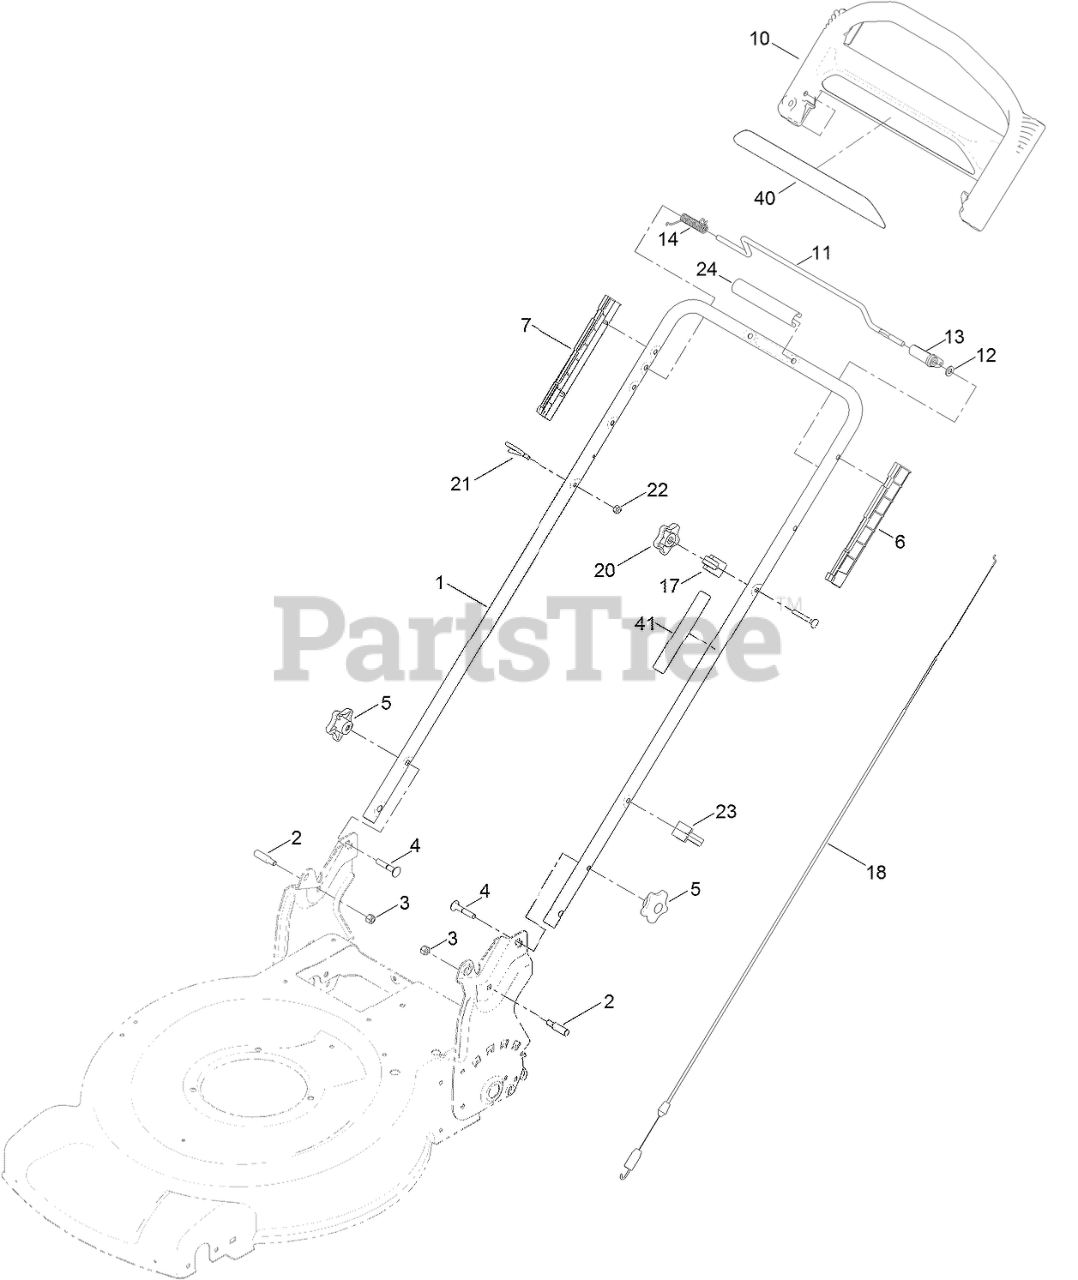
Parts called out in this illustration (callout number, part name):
2	BOLT-SHOULDER
3	NUT-LOCK, NI
4	SCREW-CARR
5	KNOB-HANDLE
6	GUIDE-LH
7	GUIDE-RH
10	HANDLE-CONTROL
11	Bar-Control, Traction
12	WASHER-PLAIN
13	LEVER-TRACTION
14	Spring-Torsion
17	ANCHOR-CABLE
18	CABLE-TRACTION
20	KNOB-HANDLE, LOCKING
21	GUIDE-ROPE
22	NUT-LOCK, NI
23	GUIDE-CABLE
24	HANDLE-COVER
41	DECAL-TRACTION, ADJUST
